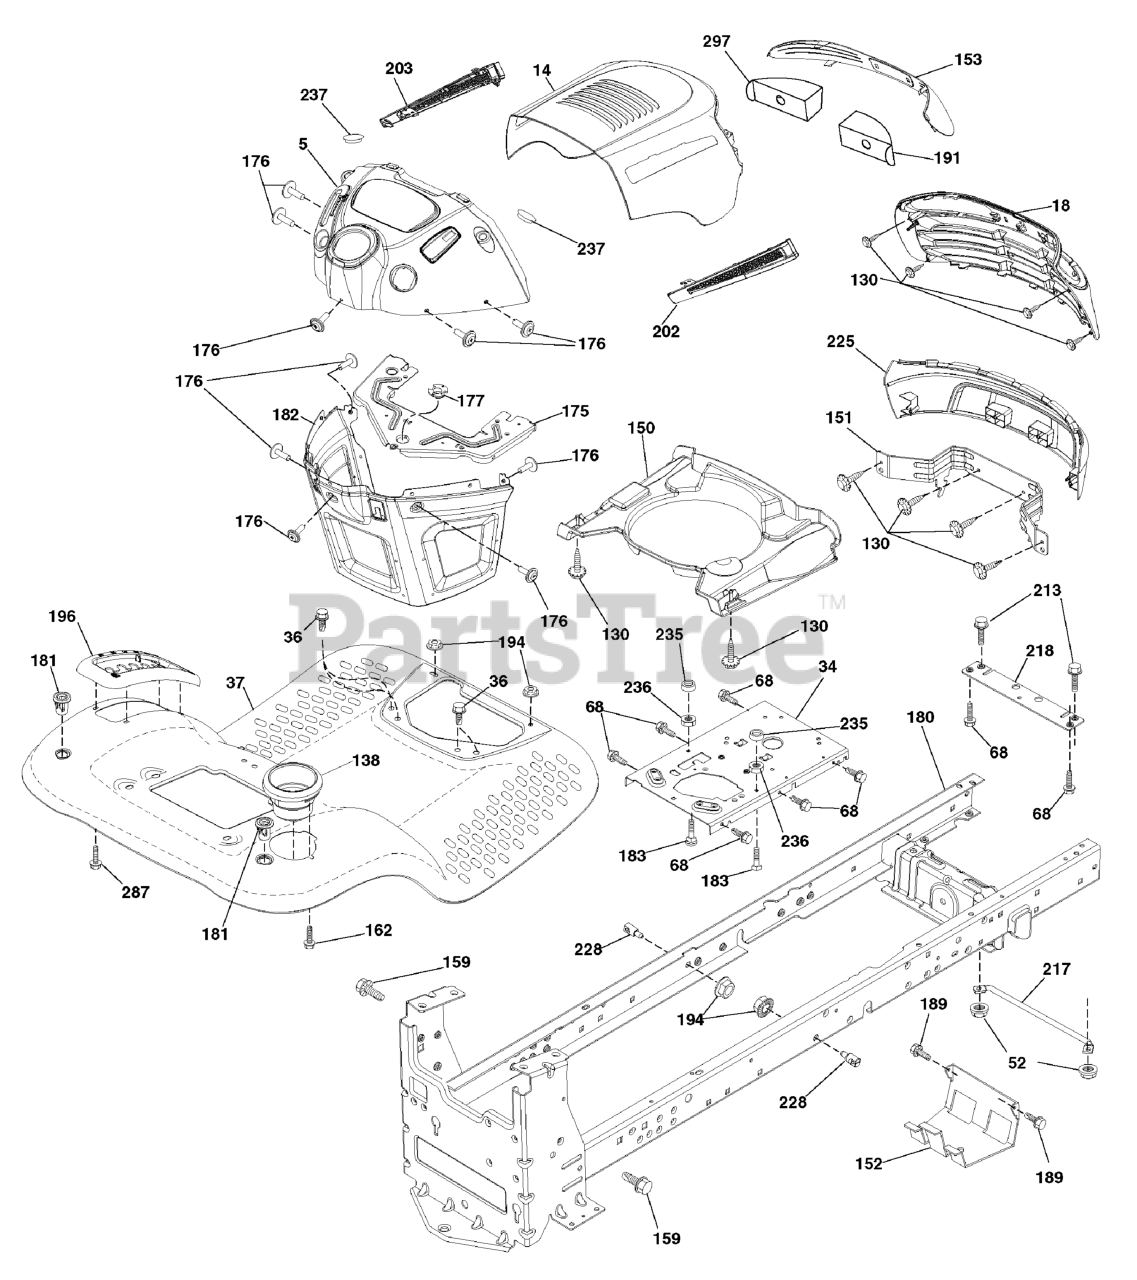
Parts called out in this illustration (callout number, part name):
15	Lens Grille LH
18	Grille Asm
34	Plate Engine
36	Screw 5/16-18 x 3/4
52	Nut Lock 5/16-18
68	Screw Thdrol 5/16-18 x 1/2
130	Screw #10 x 0.750
138	Cupholder
150	Duct Heat Hood
151	Bracket Pivot
152	Shield Browning/Debris
159	Screw 3/8-16 x 3/4
162	Screw Hex Wsh Hi-Lo 1/4 x 1/2
175	Crossmember
176	Screw 10-24 x 5/8 Wshd Qdrx
177	Bushing Steering
180	Chassis
181	Bushing Mtg. Fender Crgo.
182	Dash Lower
183	Bolt 5/16-18 x 1-1/4
189	Screw 5/16-18 x 3/4
191	Insert Reflective RH
194	Nut Lock Hex Flange 5/16-18
196	Console Asm. Deck Lift
202	Side Vent RH
203	Side Vent LH
213	Bolt 5/16-18 unc x 3/4
217	Rod Pivot Hood
218	Hood Stop
225	Bumper
228	Stud Fastener
235	Spacer Fender
236	Nut Center Lock 5/16-18
237	Plug Mount Cargo
287	1/4-20 x 3/8
297	Insert Reflective LH
